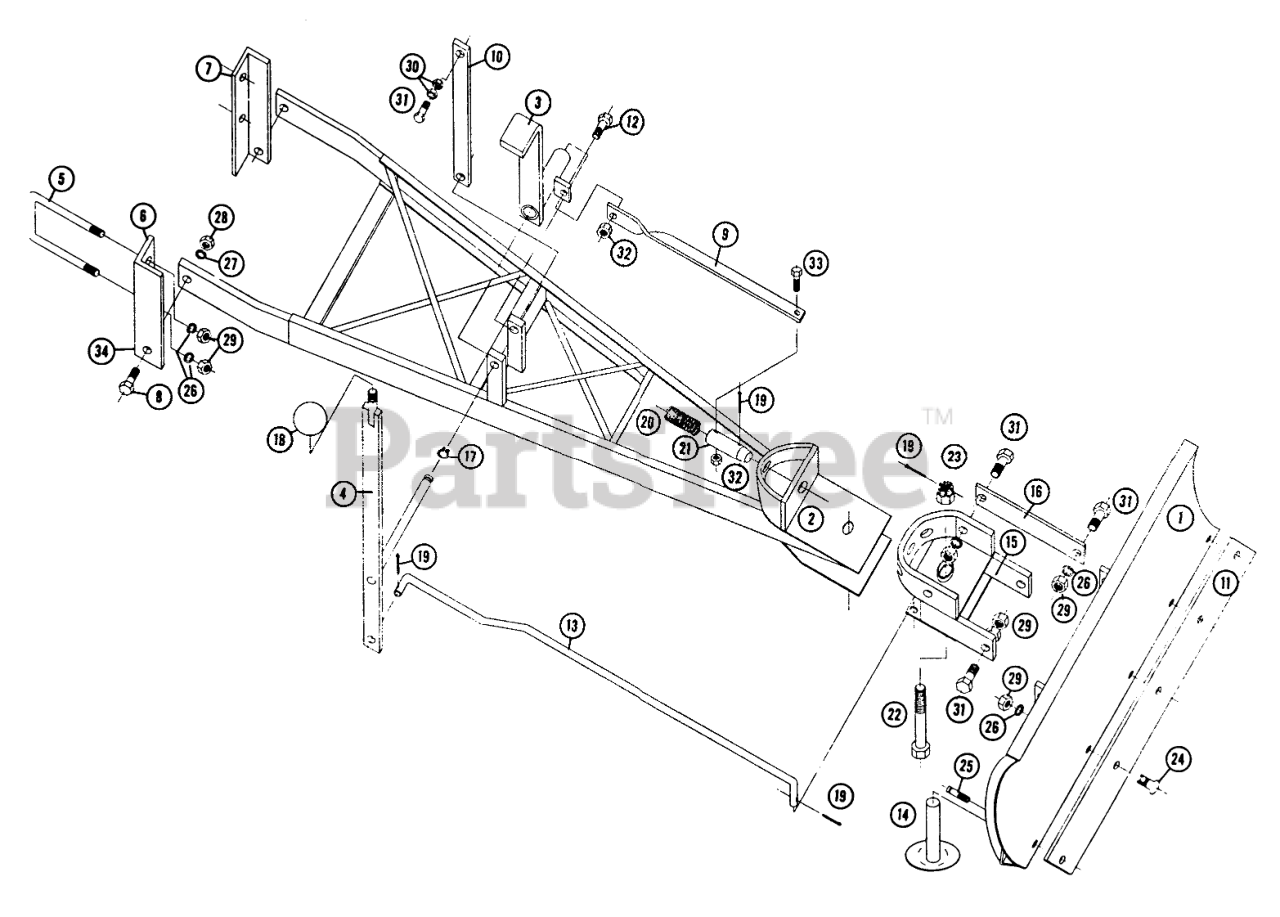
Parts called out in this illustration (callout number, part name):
1	Blade Ass-y.
2	Hitch Frame Ass-y.
3	Foot Lever Ass-y.
4	Ass-y. Lever W/A
5	U-Bolt
6	Bracket-R.H. Mtg.
7	Bracket-L.H. Mtg.
8	Bolt Shoulder
9	Bar-Trip
10	Lift Bar
11	Plate
12	Bolt-Shoulder
13	Pivot Rod
14	Skid
15	Blade-Mounting Bracket
16	Blade Pitch Brace
17	Snap Ring
18	Knob
19	Cotter Key
20	SPRING-COMPRESSION
21	Index Pin
22	Bolt-Hex 3/4-16 x 3 3/4
23	Hex Hd. Castle Nut 3/4-16
24	Carriage Bolt, 3/8 x 3/4
25	Sq. Hd. Set Screw
26	Lockwasher
27	Lockwasher
28	63543/63567 REAR MT
29	Hex Nut
30	31300 '65-67&UP 20
31	Hex Head Cap
32	Hex Nut 1/4-20
33	Hex Hd. Cap Screw
